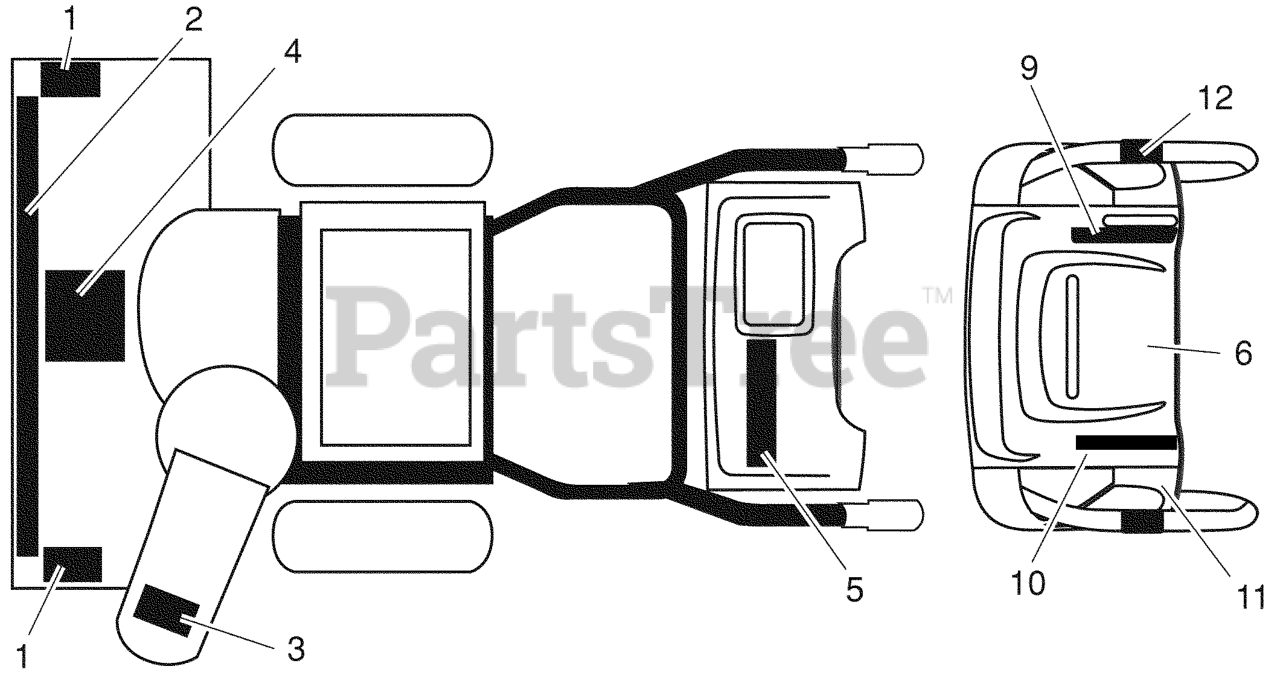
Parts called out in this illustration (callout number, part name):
1	DECAL.SNOWTHR.AUGER
3	DECAL.SNOWTHR.CHUTE.SAFETY
4	DECAL.SNOWTR.READ.OWN.MAN.E/F
6	DECAL, INSTRUCTION
7	DECAL POWER STEER
8	3ECAL POWER STEER
9	DECAL SPEED CONTROL
10	DECAL, REMOTE DEFLECTOR
